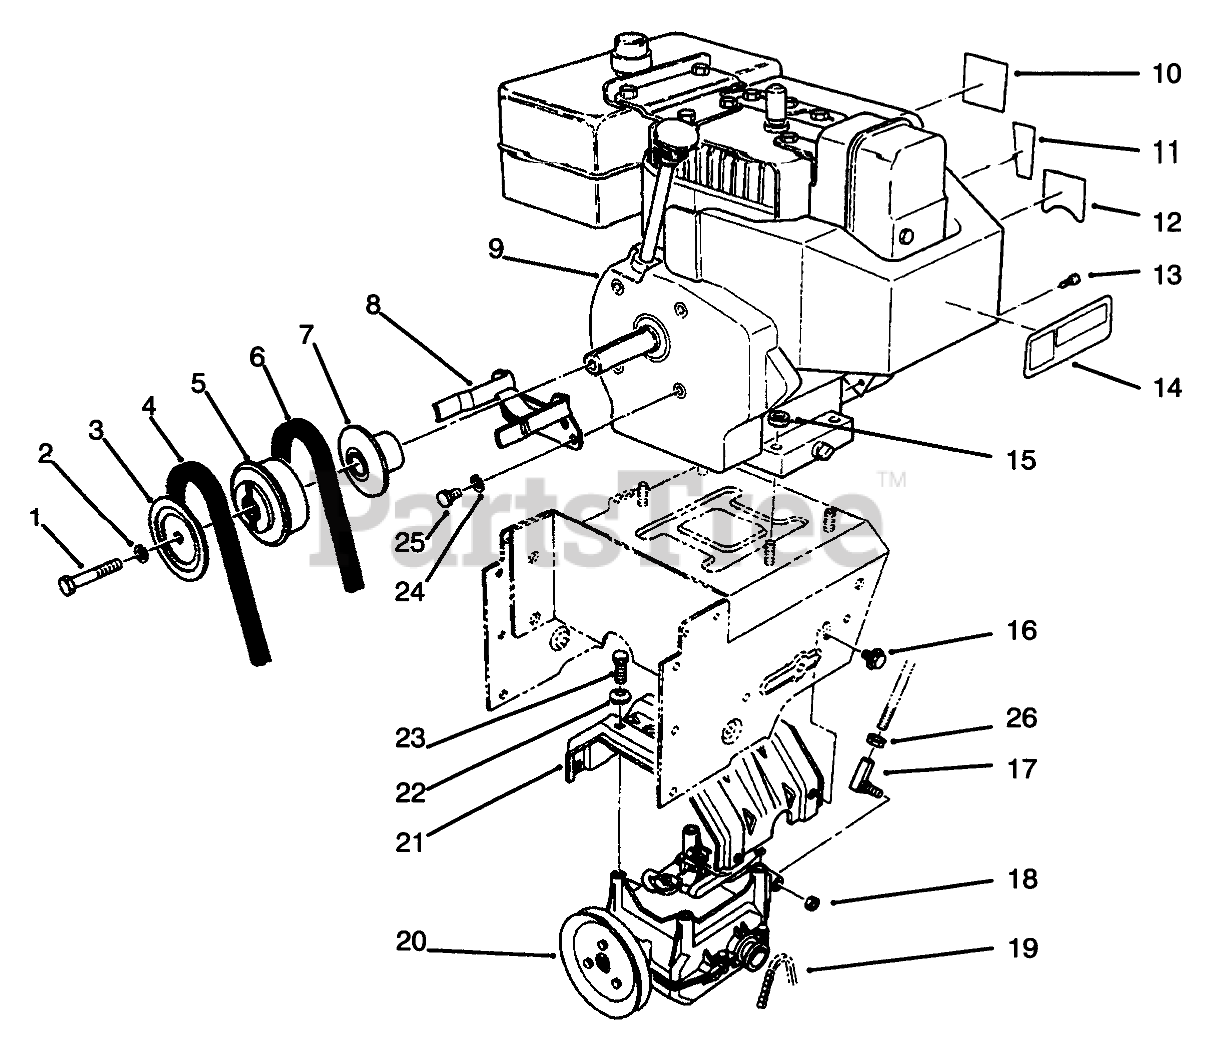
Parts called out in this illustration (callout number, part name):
1	SCREW-HH
2	WASHER-LOCK
3	SHEAVE-HALF, IMPELLER
4	V-BELT
5	PULLEY-ENGINE, CENTER
6	V-BELT-TRACTION
7	SHEAVE-HALF, TRACTION
8	Guide-Belt
10	DECAL-PRIMER
11	DECAL-THROTTLE
12	DECAL-CHOKE
13	SCREW-HWH
14	Decal-Hot Surface
15	NUT-HF
16	SCREW-HHF
17	JOINT-BALL
18	NUT-LOCK, NI
19	CHAIN
20	TRACTION GEARCASE ASM
21	Frame-Transmission
22	WASHER-SPRING
23	SCREW-HWHTF
24	WASHER-LOCK
25	SCREW-HH
26	NUT-HJ
